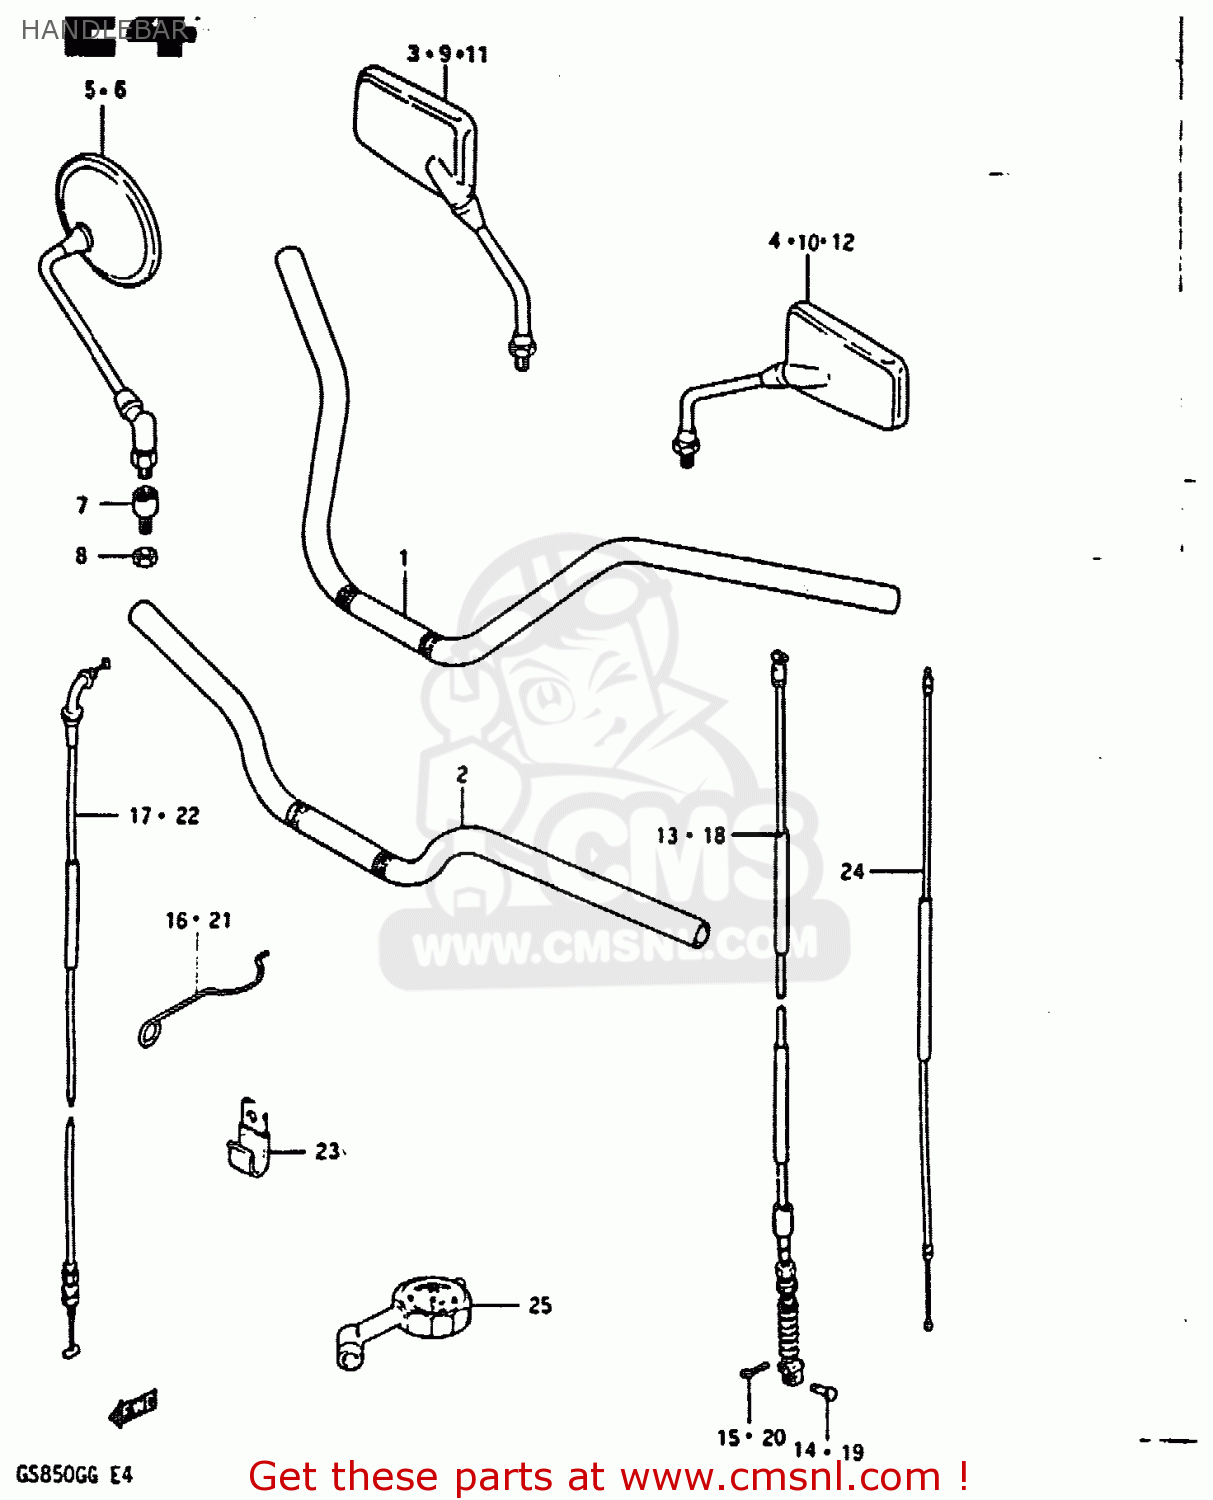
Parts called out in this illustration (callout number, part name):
1	HANDLEBAR
2	HANDLEBAR (FLAT)
3	MIRROR, REAR VIEW RH
4	MIRROR, REAR VIEW LH
5	MIRROR ASSY,RH
6	MIRROR, REAR VIEW LH
7	CUSHION,REAR VIEW MIRROR
8	NUT
9	MIRROR, REAR VIEW RH
10	MIRROR, REAR VIEW LH
11	MIRROR, REAR VIEW RH
12	MIRROR, REAR VIEW LH
13	CABLE ASSY,CLUTCH
14	PIN(L:15)
15	PIN
16	GUIDE,CABLE
17	CABLE ASSY,THROTTLE
18	CABLE ASSY,CLUTCH
19	PIN(L:15)
20	PIN
21	GUIDE,CABLE
22	CABLE ASSEMBLY,THROTTLE
23	CLAMP
24	CABLE,STARTER
25	GAUGE ASSY,AIR PRESSURE
